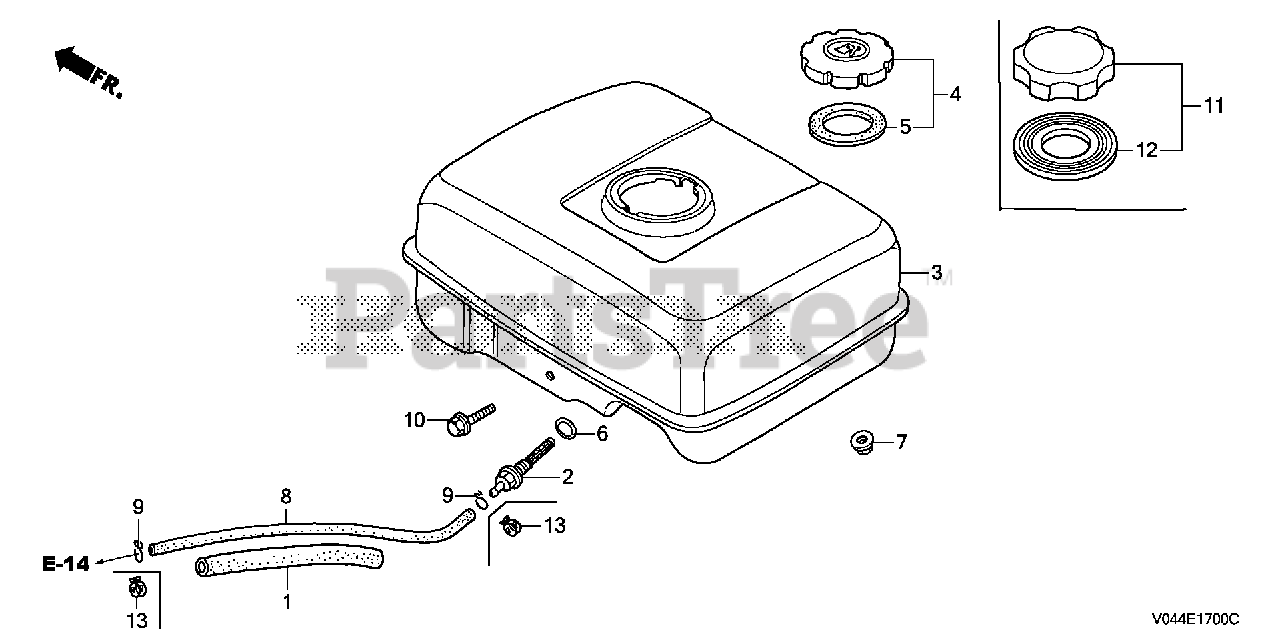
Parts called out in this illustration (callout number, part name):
1	RUBBER, SUPPORTER (107MM)
2	JOINT, FUEL TANK
3	TANK, FUEL *R280* (POWER RED)
6	O-RING (13.5X1.5) (ARAI)
6	O-RING (14MM) (NOK)
7	NUT, FLANGE (6MM)
8	TUBE, FUEL (4.5X140) (FKM)
9	CLIP, TUBE (B8)
10	BOLT, FLANGE (6X34)
11	CAP, FUEL FILLER (CHROME PLATED)
12	GASKET, FUEL FILLER CAP (39X62X3) (TOUYOUSYA)
13	CLAMP, TUBE (D8)
